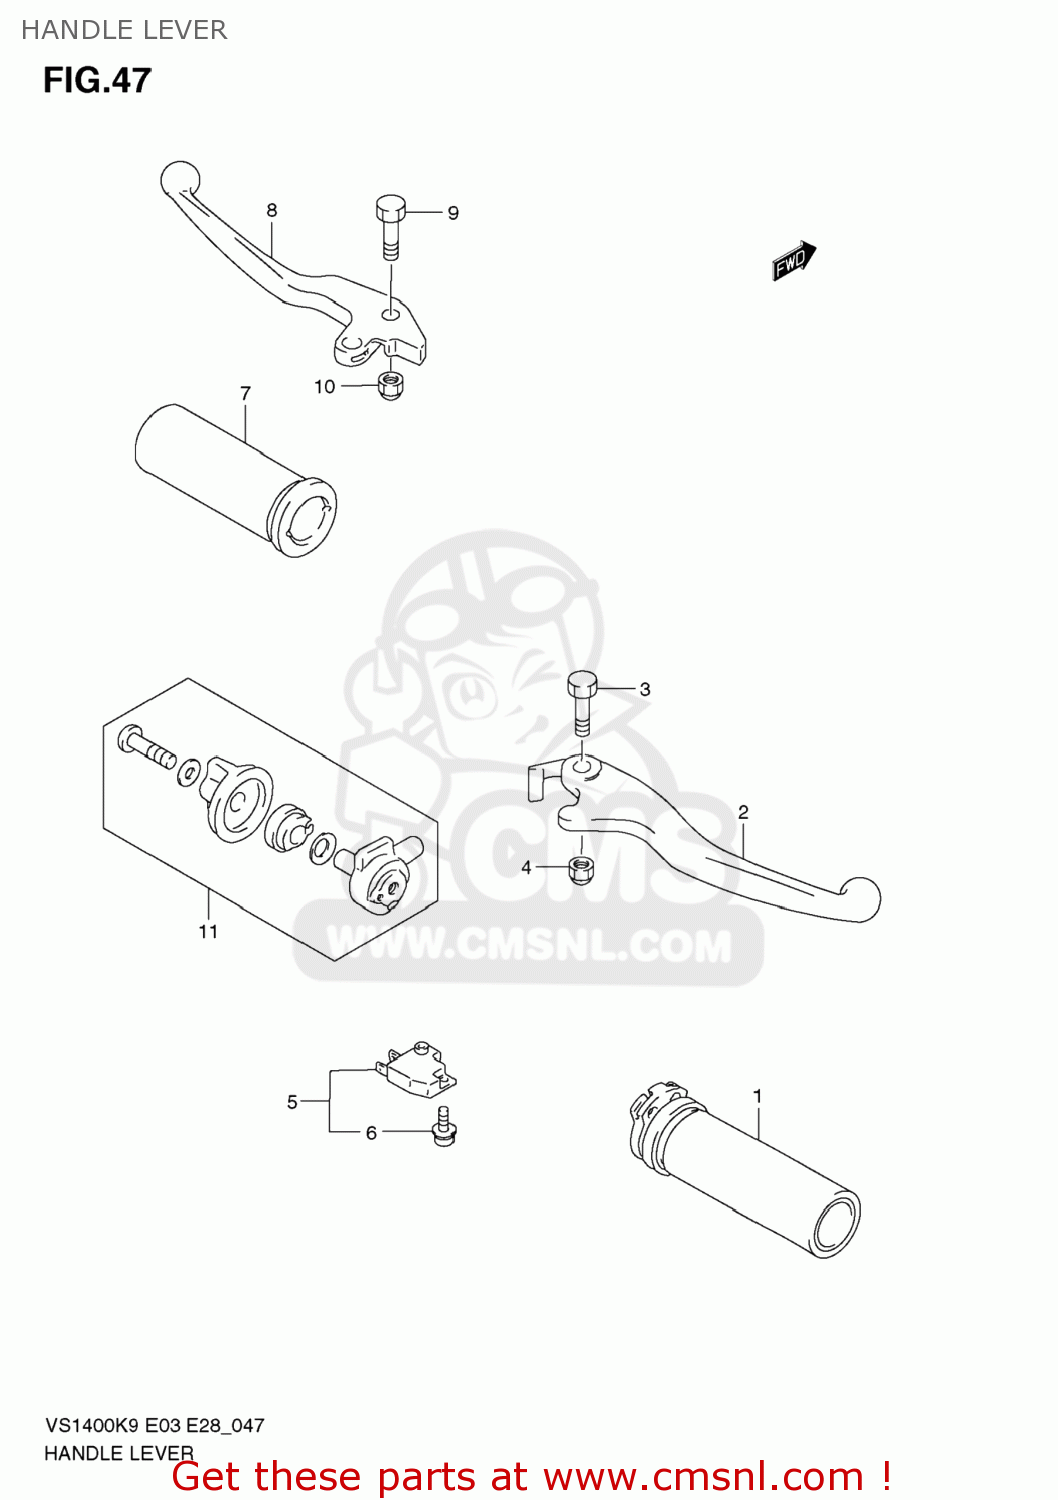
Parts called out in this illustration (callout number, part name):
1	GRIP,THROTTLE
2	LEVER,BRAKE
3	BOLT,LEVER SET
4	NUT
5	SWITCH ASSY,ST
6	SCREW
7	GRIP,L
8	LEVER,CLUTCH (SILVER)
9	BOLT,LEVER SET
10	NUT
11	LEVER ASSY,STARTER
